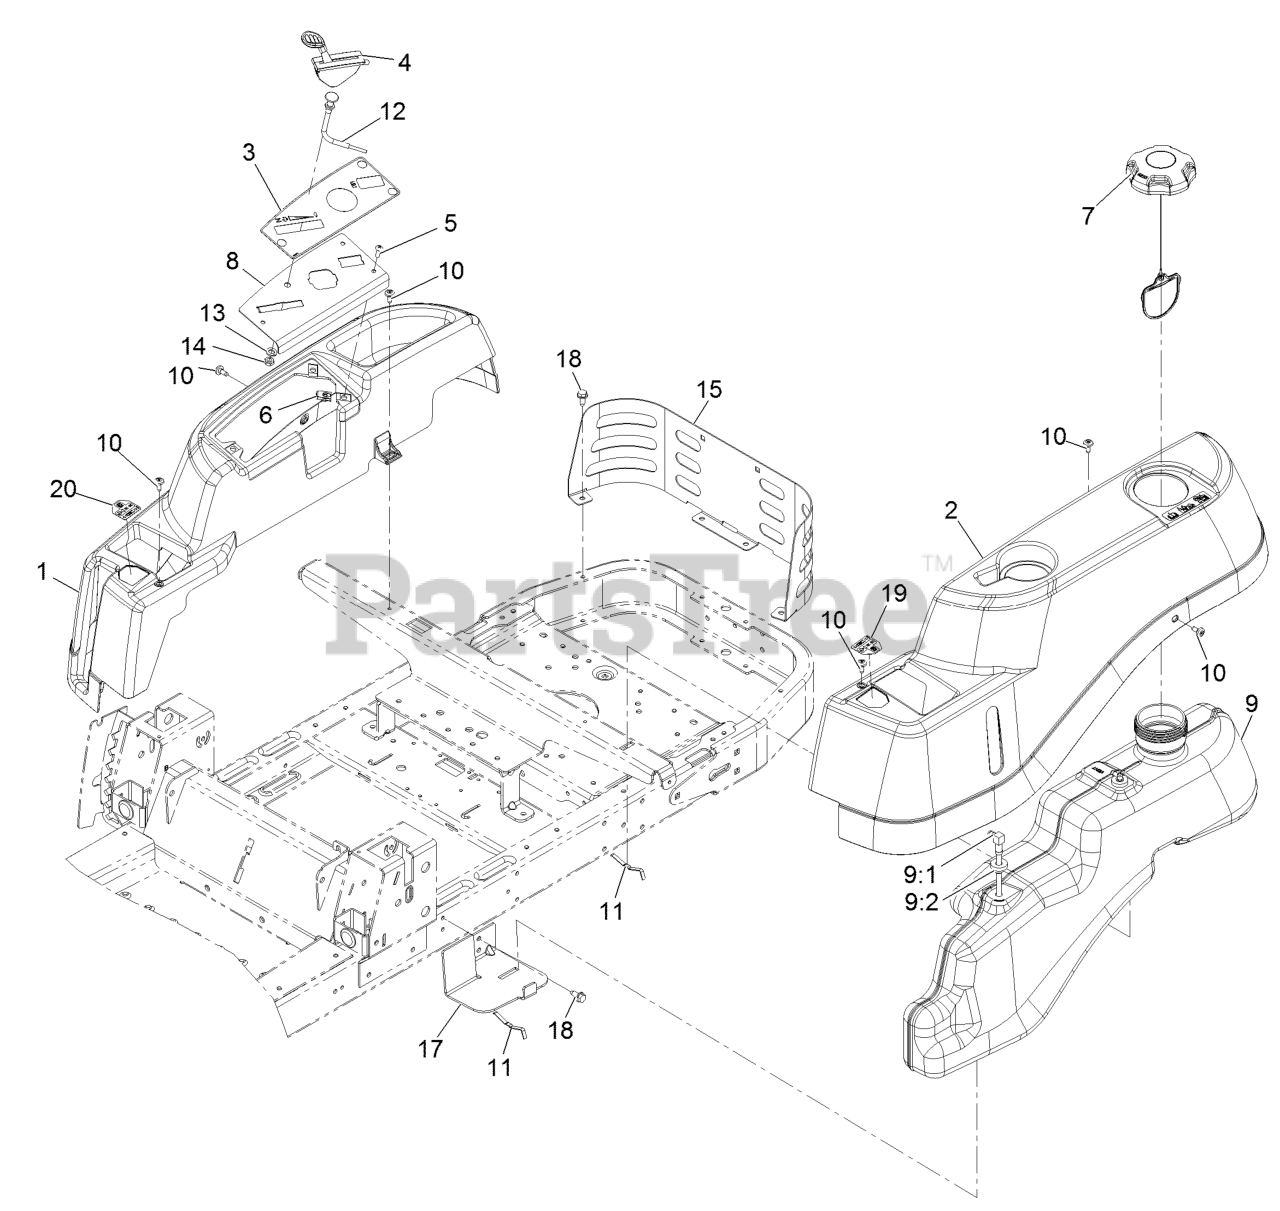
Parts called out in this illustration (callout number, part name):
3	DECAL-PANEL, CONTROL
4	CABLE-THROTTLE
5	SCREW-PRH
6	Nut-Retainer-Panel 1/4-20
8	PLATE-CONTROL
9	FUEL TANK ASM
9:1	CONNECTOR-ELBOW, 90 DEG
9:2	BUSHING
10	SCREW-SHOULDER
11	SPRING
12	CABLE-CHOKE
13	WASHER-LOCK
14	NUT-HJ
15	GUARD-REAR
17	SUPPORT-TANK, FRONT
18	Screw-HWH 5/16-18 X 3/4 Tf
19	DECAL-LEVER, CONTROL (LH)
20	DECAL-LEVER, CONTROL (RH)
